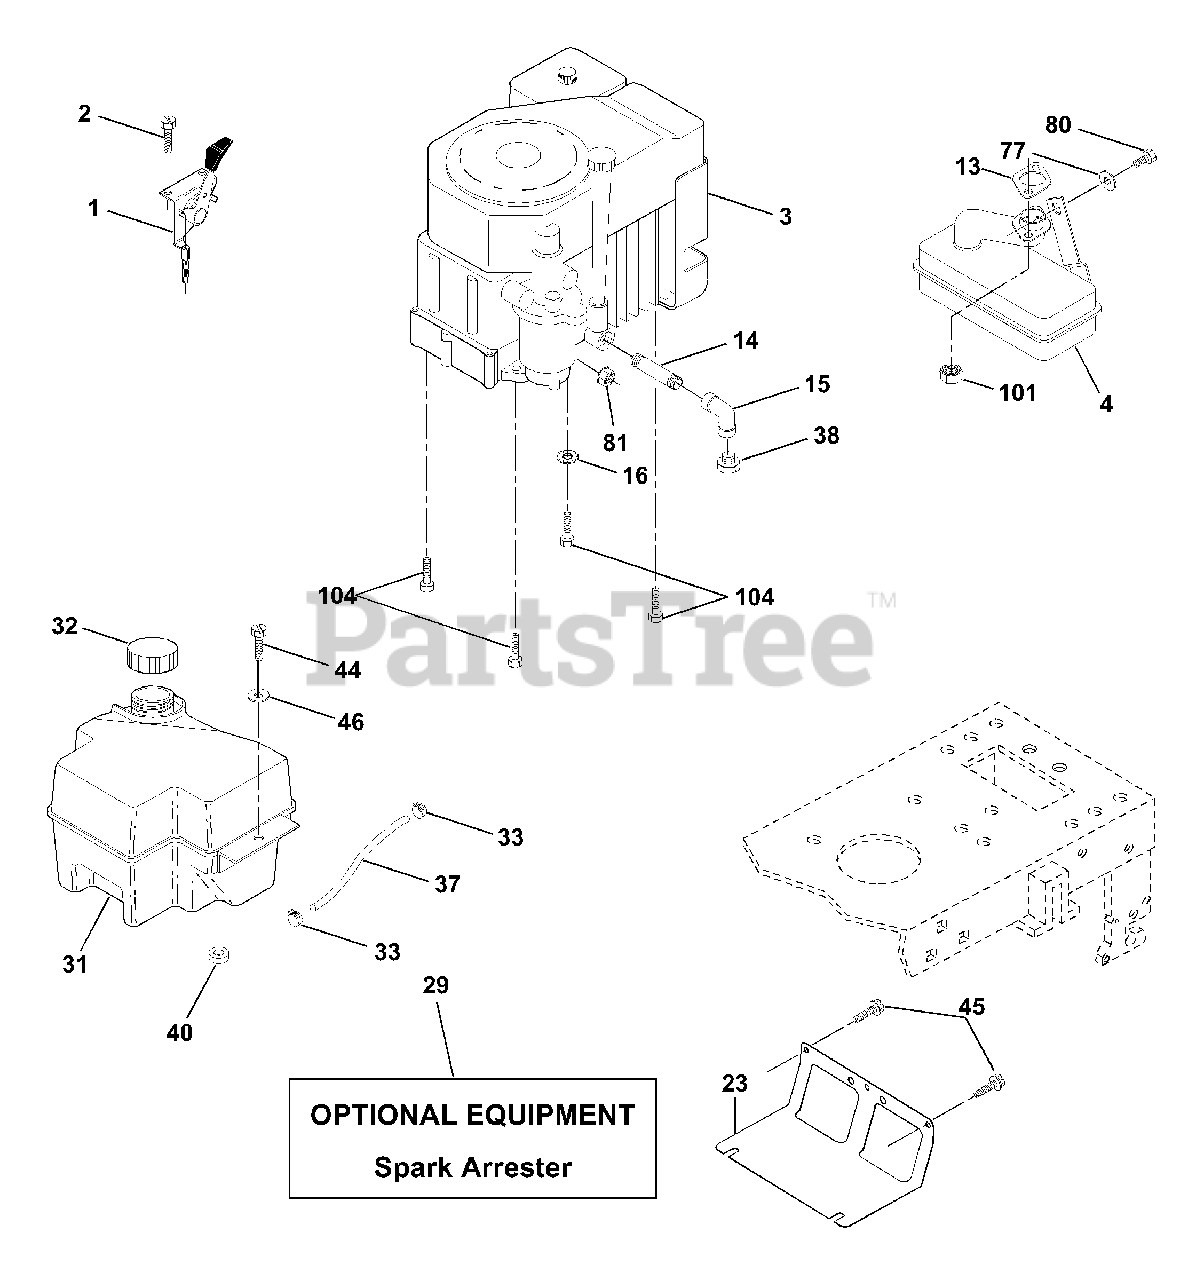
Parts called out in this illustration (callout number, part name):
1	Control THTICH 27 LH FLAG DOM
2	Screw Hex Thd Cut 1/4-20 x 5/8 T
13	Gasket Kohler CV13-CV16.5
14	Nipple Pipe 3/8 Npt X 3-1/2
15	Elbow Std 90 Degree 3/8-18 Npt
16	Washer Lock Ext Tooth 3/8
23	Shield Browning/Debris Guard
29	Kit Spark Arrestor (Flat Scrn)
31	Tank Fuel Front 2 00 Gal Nat
32	Cap Asm Fuel W/sym Vented
33	Clamp Hose Black
37	Line Fuel 20"
38	Plug Oil Drain
40	Bushing Snap Nyl Blk Fuel Line
44	Screw Hexwsh Thdrol 1/4-20x3/4
45	Screw 3/8-16 x 3/4
46	Washer 9/32 X 7/8 X 16 Ga
77	Washer 5/16 x 3/4 x 16 Ga.
80	Bolt Hex Hd 5/16-18 UNC x 1/2
81	Nut Flange 1/4-20 Starter Nut
101	Nut Flange Me-1.25 Non-LK
104	Screw 3/8-16 x 1-1/2
